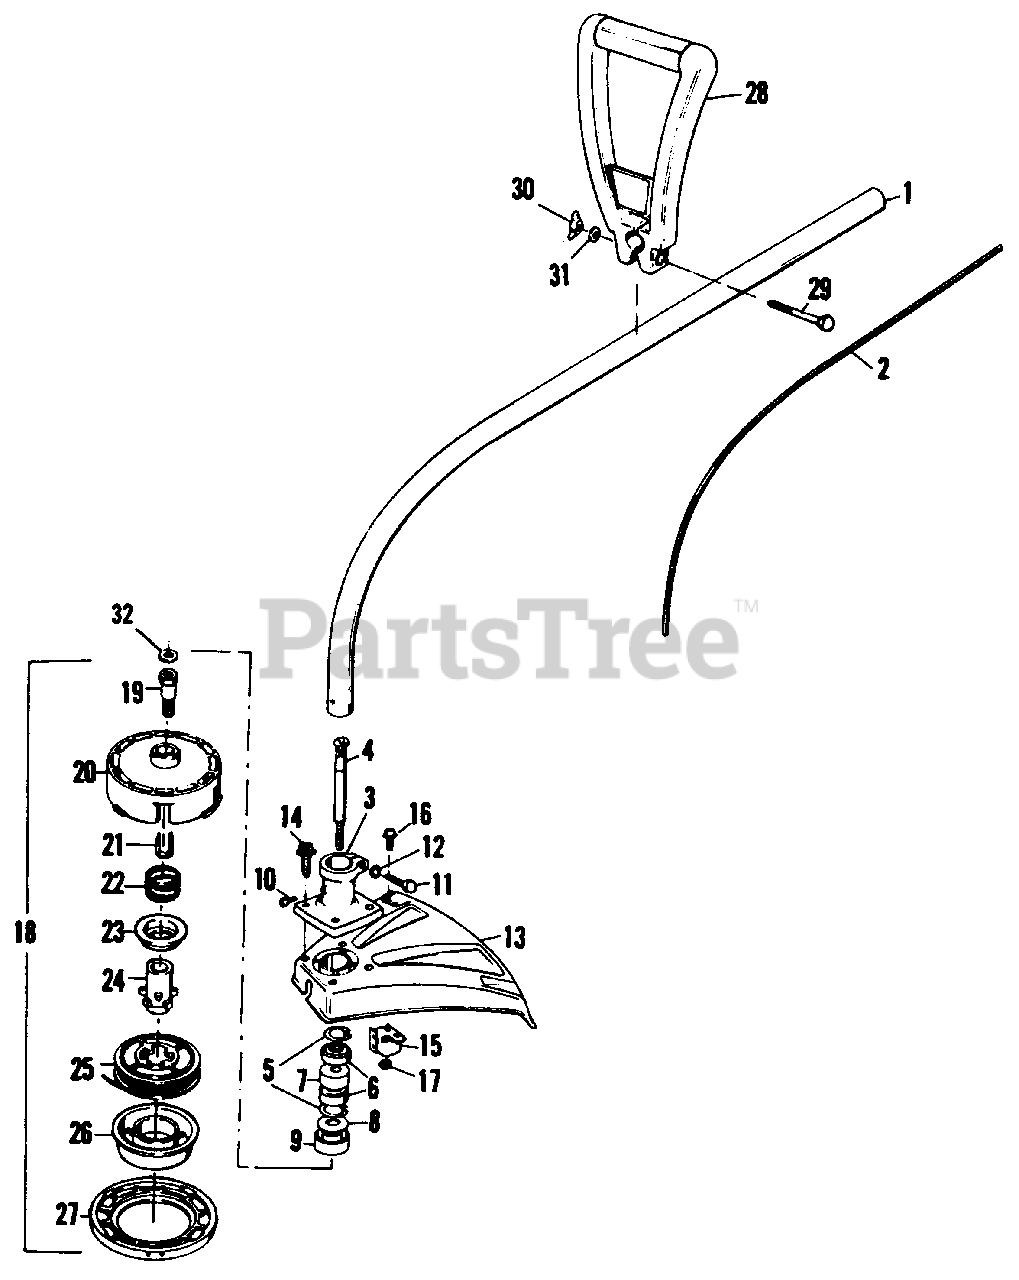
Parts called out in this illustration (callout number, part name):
1	Drive Shaft Housing 1700
1	Drive Shaft Housing 1600
2	Drive Shaft 1600
2	Drive Shaft 1700
3	Bearing Housing Assy
4	Shaft-Arbor
5	Retainer-Bearing
6	Bearing
7	Spacer-Bearing
8	Washer-Dust Cup
9	Dust Cup
10	Screw-Self-Tapping
11	Screw-Pinch Clamp
12	Washer-1/4 Int. Tooth Lock
13	Splash Deflector 1700
13	Splash Deflector 1600
14	Screw-Shield to Bearing Hsg
15	Line Limiter
16	Screw-Line Limiter
17	Nut-Locking
18	Cutting Head Assy.
19	Bolt-Drive Adaptor
21	Line Saver
23	Adaptor-Spring
24	Drive Gear
25	Spool w/Line
26	Release Button
28	Assist Handle 1600
28	Assist Handle 1700
29	Hex Bolt-1/4-20 x 1-1/2
30	Wing Wing Nut-1/4-20
31	Washer-1/4 Flat
32	Grass Washer
